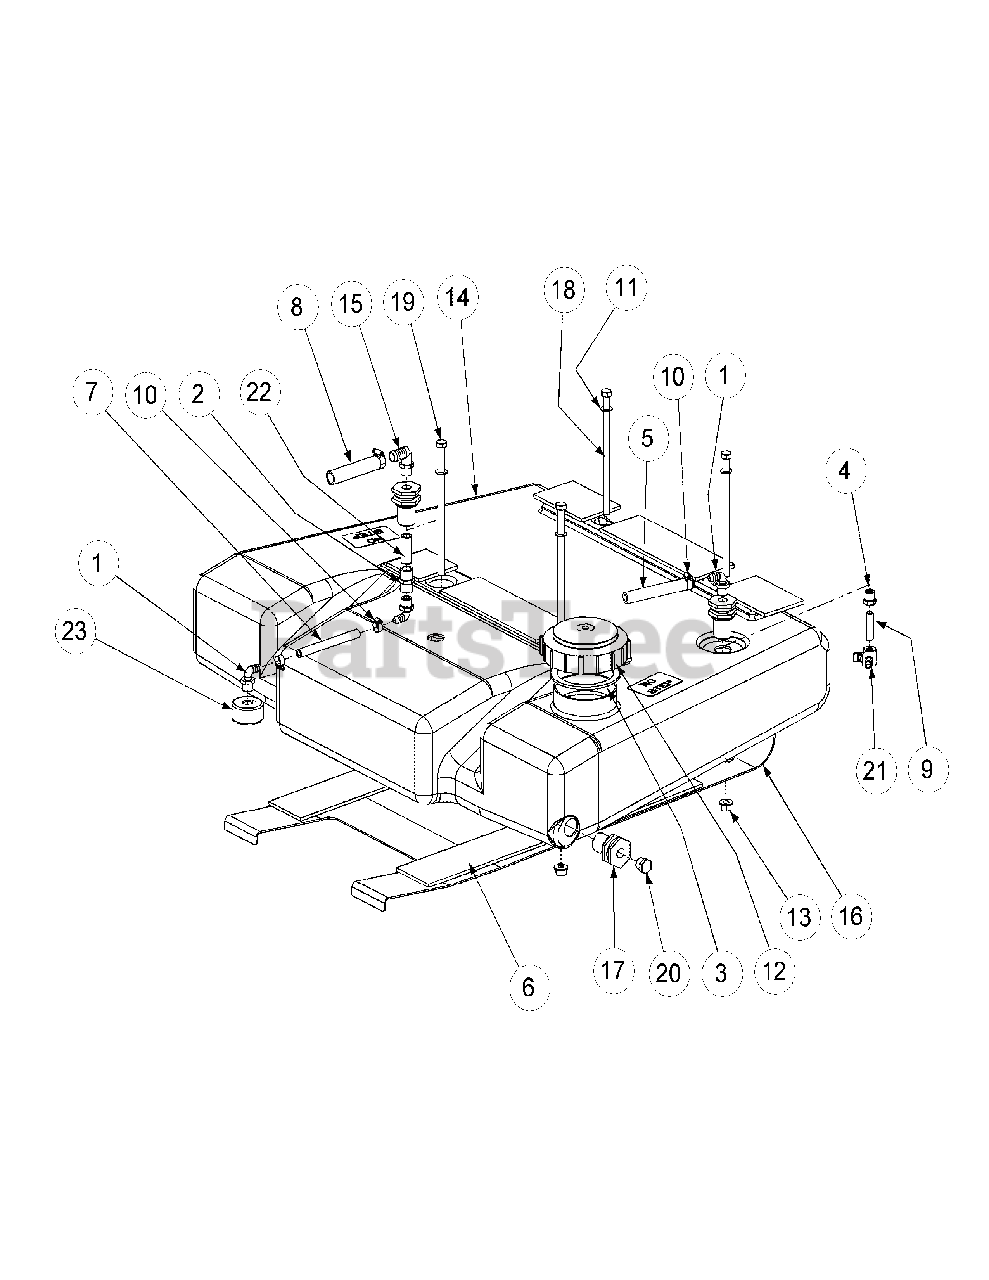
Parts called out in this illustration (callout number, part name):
1	Hose Barb, 1/2 NPT, 1/2 Nylon
2	Coupling, 1/2" (F) NPT
4	Adapter, 1/4 NPT, 1/2 NPT
5	Hose, 1/2" sold by the ft.
6	Foam, Adhesive Backed, 4'' x 1/4'' by ft.
7	Hose, 3/8 by the ft.
8	Hose, 3/4 by the ft.
9	Nipple, 1/4 NPT x 2"
10	Hose Clamp, 1/2, 7/8
11	Flat Washer, .536 ID x .93 OD x .050
13	Nut, 1/2-20
14	Tank, 40 Gallon
15	Hose barb, 1/2 NPT, 3/4 Elbow
16	Tank Skid Plate
17	Fitting, 1/2 Double Threaded
18	Hex Head Cap Screw, 1/2-20 x 9.00
19	Hex Head Cap Screw, 1/2-20 x 9.50
20	Pipe Plug, 1/2 NPT
21	Jet Agitator
22	Nipple, 1/2"-14 x 2.00
23	Fitting, Tank
